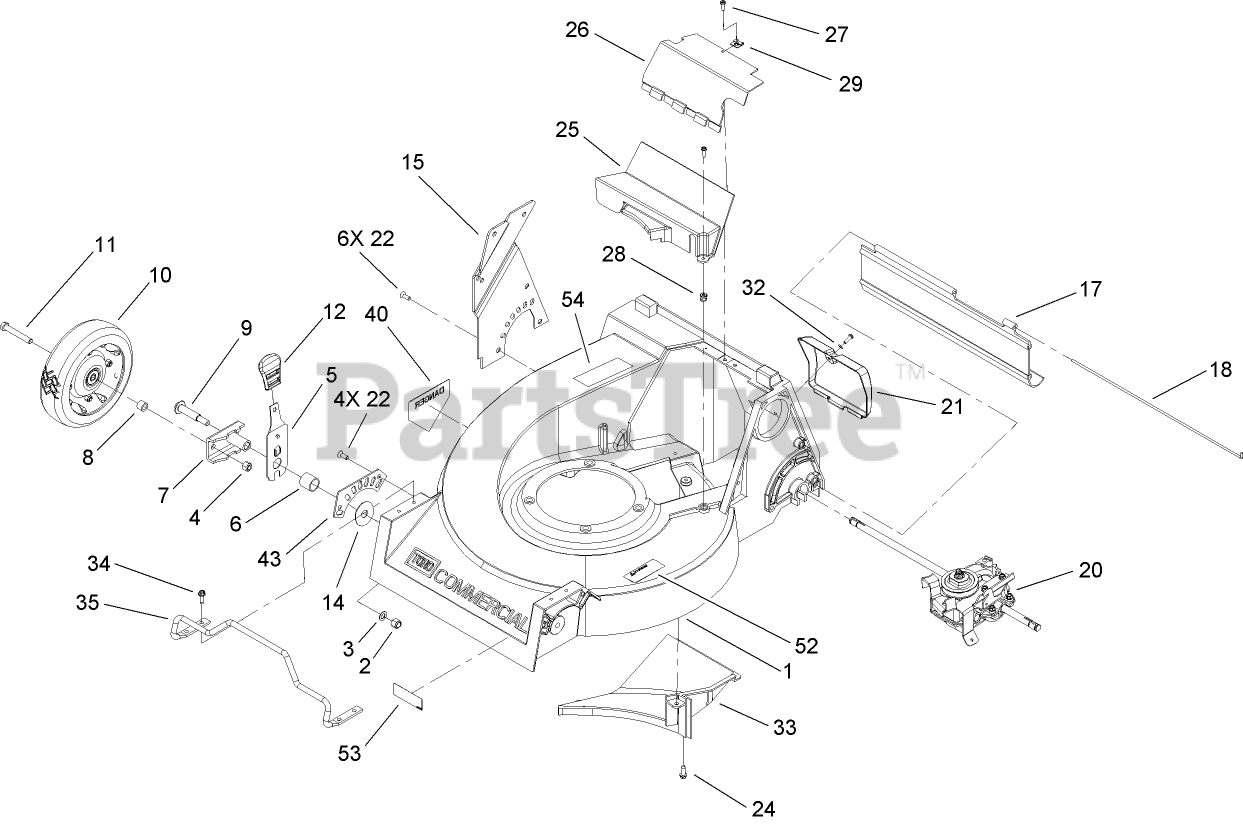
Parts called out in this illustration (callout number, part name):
1	HOUSING
2	NUT-LOCK
3	WASHER
4	NUT-LOCK, CONE
5	SPRING ARM ASM
6	SPACER-BEARING
7	ARM-PIVOT, FRONT
8	SPACER-WHEEL
9	BOLT-WHEEL
10	Wheel and Tire ASM
11	SCREW-HH
12	KNOB-HOC
14	WASHER-PLAIN
15	PLATE-REAR HOC, RH
17	SHEILD-TRAILING
18	ROD-SHIELD
20	GEAR CASE ASM
21	DOOR-ACCESS, REAR
22	SCREW-HH
24	SCREW-HWHTF
25	COVER-BELT, LOWER
26	COVER-BELT, UPPER
28	NUT-CLIP
29	NUT-TYPE J
32	WASHER-FLAT
33	BAFFLE-CHUTE, FLOOR
34	SCREW-HWHTF
35	GUARD-ENGINE
40	DECAL-DANGER
43	PLATE-FRONT HOC, RH
52	DECAL-WARNING
53	DECAL-BLADE
54	DECAL-DANGER
